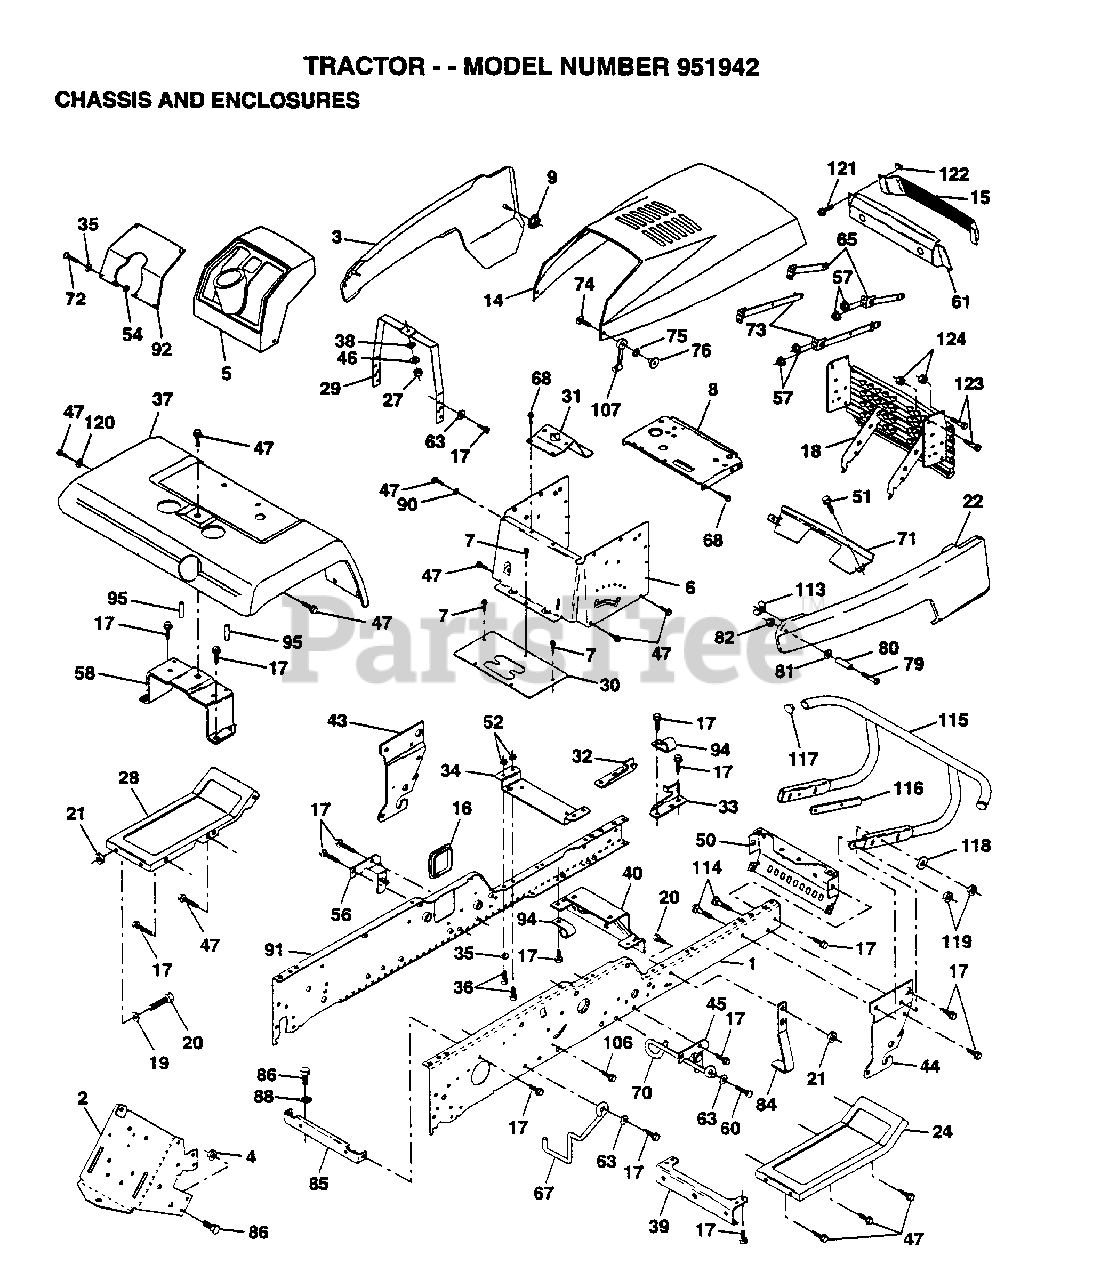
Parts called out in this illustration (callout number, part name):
2	DRAWBAR GT
4	NUT.7/16
5	DASHBOARD BLACK
6	DASH.1PC.LOWER
7	SCREW
8	SUPPORT.DASH.BTRY
9	PAL NUT LT
15	LENS LT
16	COVER ACCESS
17	SCREW
19	WASHER
20	BOLT
22	PANEL SIDE RH
24	FOOTREST.RH.LT/GT
28	FOOTREST.LH.LT/GT
29	DASH.SUPT.YP/HUSQ
30	SADDLE.SCR.6SP
31	BRAKET.SUPT.STEER
32	BRACKET ASM FRAME
33	BRACKET ASM FRAME
34	BRACKET.ENG.SUPT.
35	WASHER
36	BOLT
37	FENDER
38	WASHER PM
39	BRACKET.AXLE.FRT.
43	BRACKET.SUS.FT.LH
44	BRACKET.SUS.FT.RH
46	LOCKWASHER
47	SCREW LT
50	BRACKET.CHASSIS.
51	SCREW CRT
57	NUT HXKEP 1/4X20
58	BRKT.ASM.FENDER
60	SCREW
62	BOLT D
63	WASHER
67	GUIDE BELT TRANS
68	SCREW LT
70	GUIDE.BELT.MID.SP
71	STRAP.GRILLE.PNT.
72	SCREW
74	SCREW
75	LOCKWASHER
76	WELDNUT
79	SCREW
80	SPACER LT
81	WASHER
84	STOP.OVER.CENTER
85	BRACKET.SUPT.TRAN
86	BOLT
88	LOCKWASHER
90	LOCKWASHER
92	PLATE YP SLKSCR
94	CLIP GTV
95	NUT-PUSH YT
107	HOOD LATCH T
114	BOLT.3/8-14X1.25
115	BUMPER.ASM.W/PY
116	BRACKET.EXT.BUMP.
117	PLUG.PLASTIC
118	WASHER
120	WASHER HYT
122	"""J"" FASTENER LT"
124	NUT
